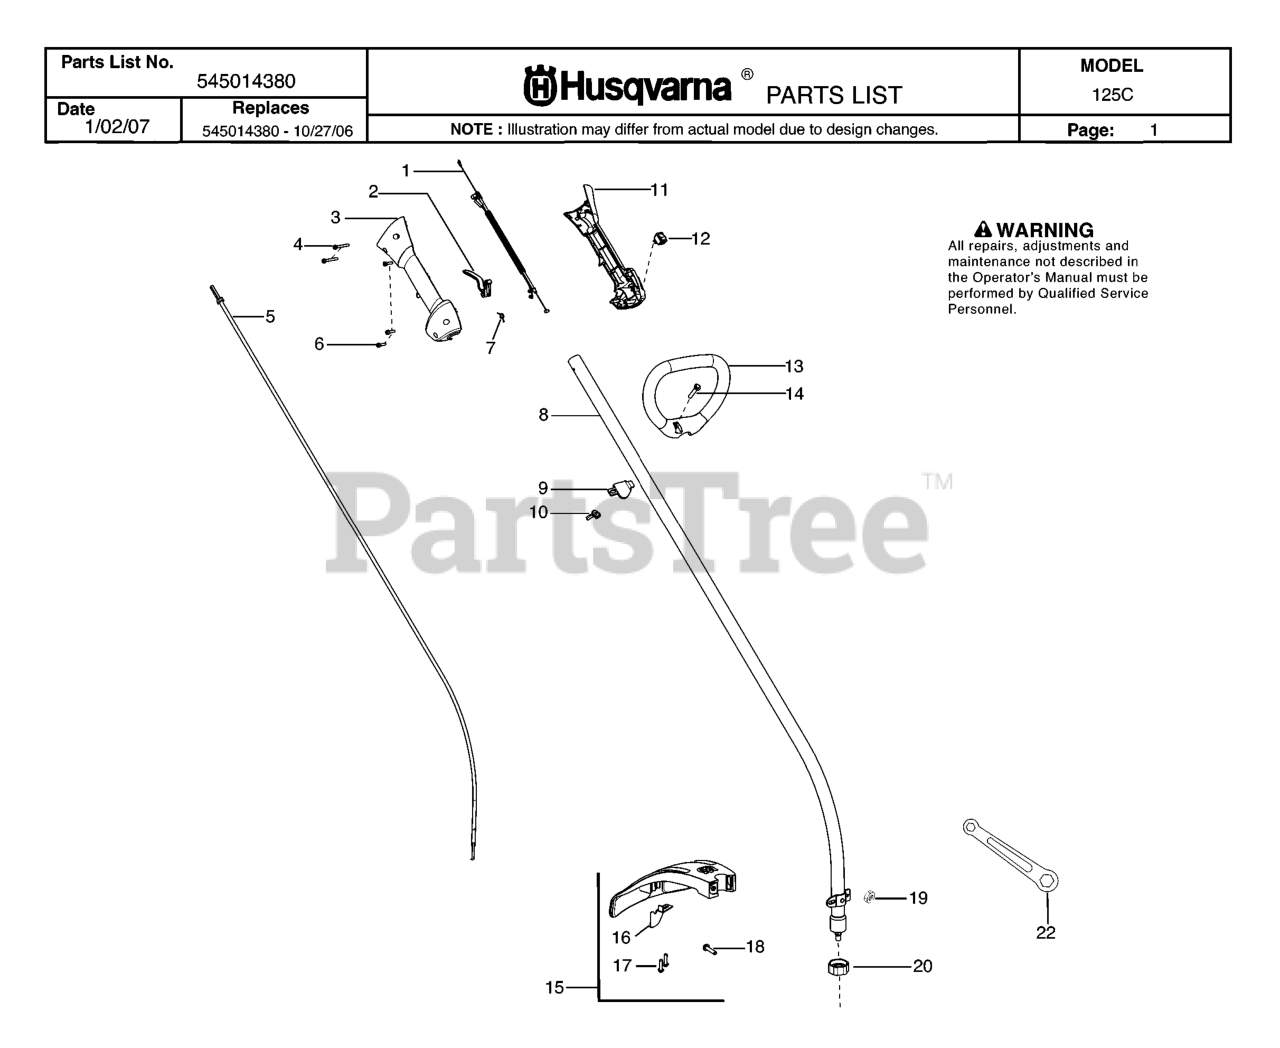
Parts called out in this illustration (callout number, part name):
2	TRIGGER THROTTLE
3	HOUSING-THROTTLE (RH)
5	FLEX SHAFT 52"
6	SCREW M4 X 1.75 PT 16MM
7	SPRING TRIGGER
8	DRIVE SHAFT ASSY
9	CLAMP ASSIST HANDLE
10	WINGNUT, TYPE 2
11	HSG THROTTLE LH
12	KIT SWITCH
14	BOLT, TYPE 2
18	BOLT, TYPE 2
